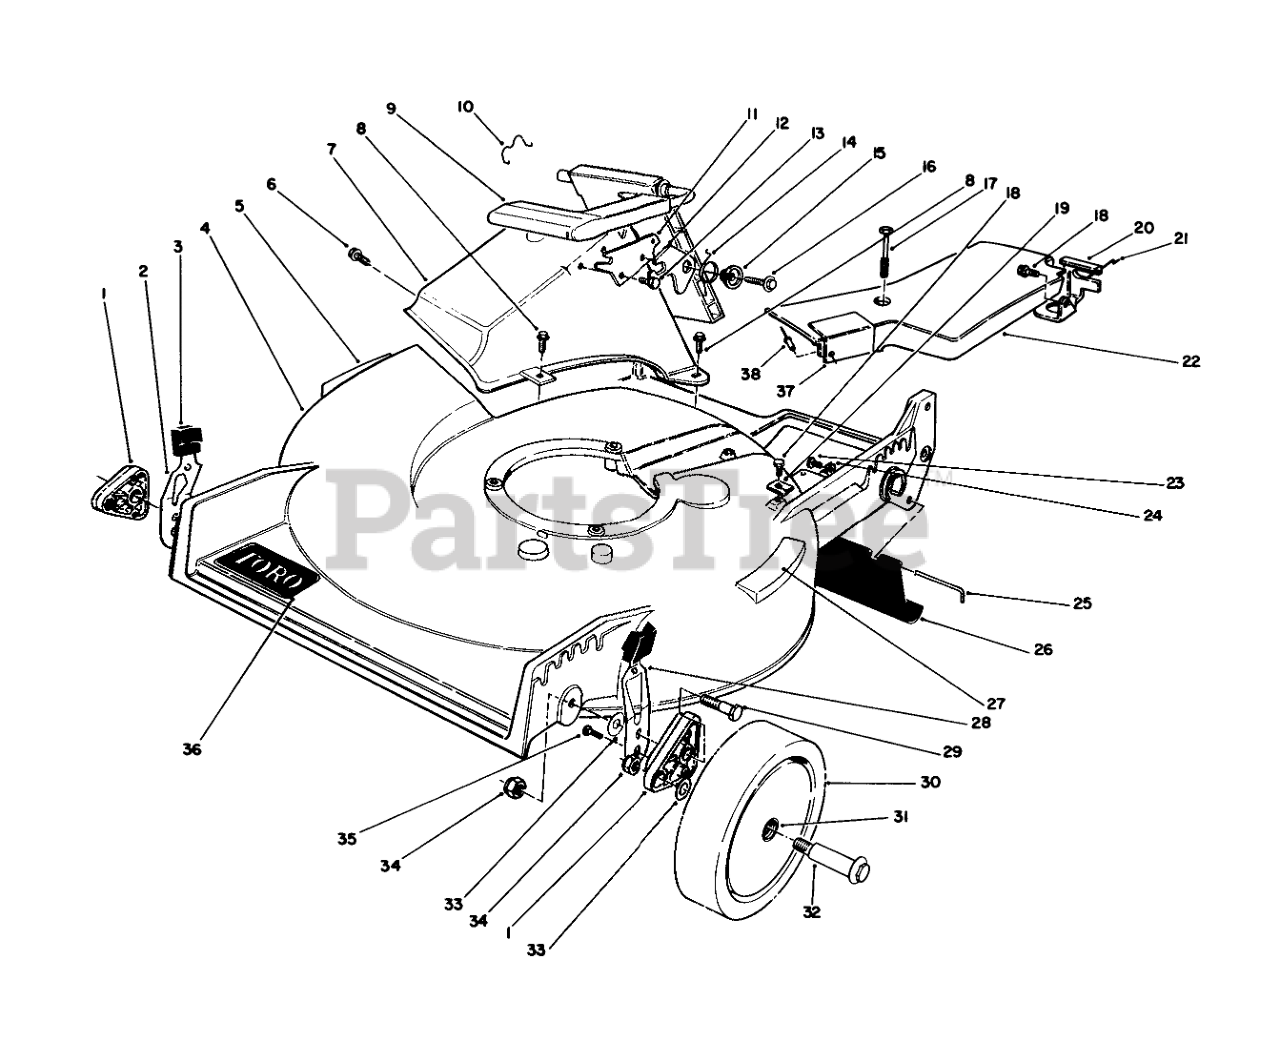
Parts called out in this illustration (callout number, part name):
1	ARM-PIVOT, FRONT
2	RH SPRING ARM ASSEMBLY
3	KNOB-ARM
4	Housing (Incl. Ref. #5, 27 & 36)
5	DECAL-DANGER
6	SCREW AND WASHER ASM
7	Tunnel Discharge
8	SCREW-HWH
9	Discharge Door Assembly
10	DOOR RET SPRING
11	DOOR LATCH PLATE
12	SAFETY LATCH
13	SCREW-PLASTITE
14	TORSION SPRING
15	DOOR SPACER
16	SCREW-HWH
17	SCREW-HHFTF
18	SCREW-HWHTF
19	CLAMP-CABLE
20	Bracket-Traction Adj.
21	RETAINER-CABLE
22	BELT COVER ASM
23	SCREW
24	CLAMP-CABLE
25	ROD-SHIELD
26	SHIELD-TRAILING
27	STEP PAD DECAL
28	LH SPRING ARM ASSEMBLY
29	SCREW-SHOULDER
30	Wheel & Tire Assembly (Incl. Ref. #31)
31	BUSHING
32	WHEEL BOLT
33	WASHER
34	Nut
35	SCREW-HWH
36	DECAL
37	HEAT SHIELD
38	RIVET-HEAD, FLAT
